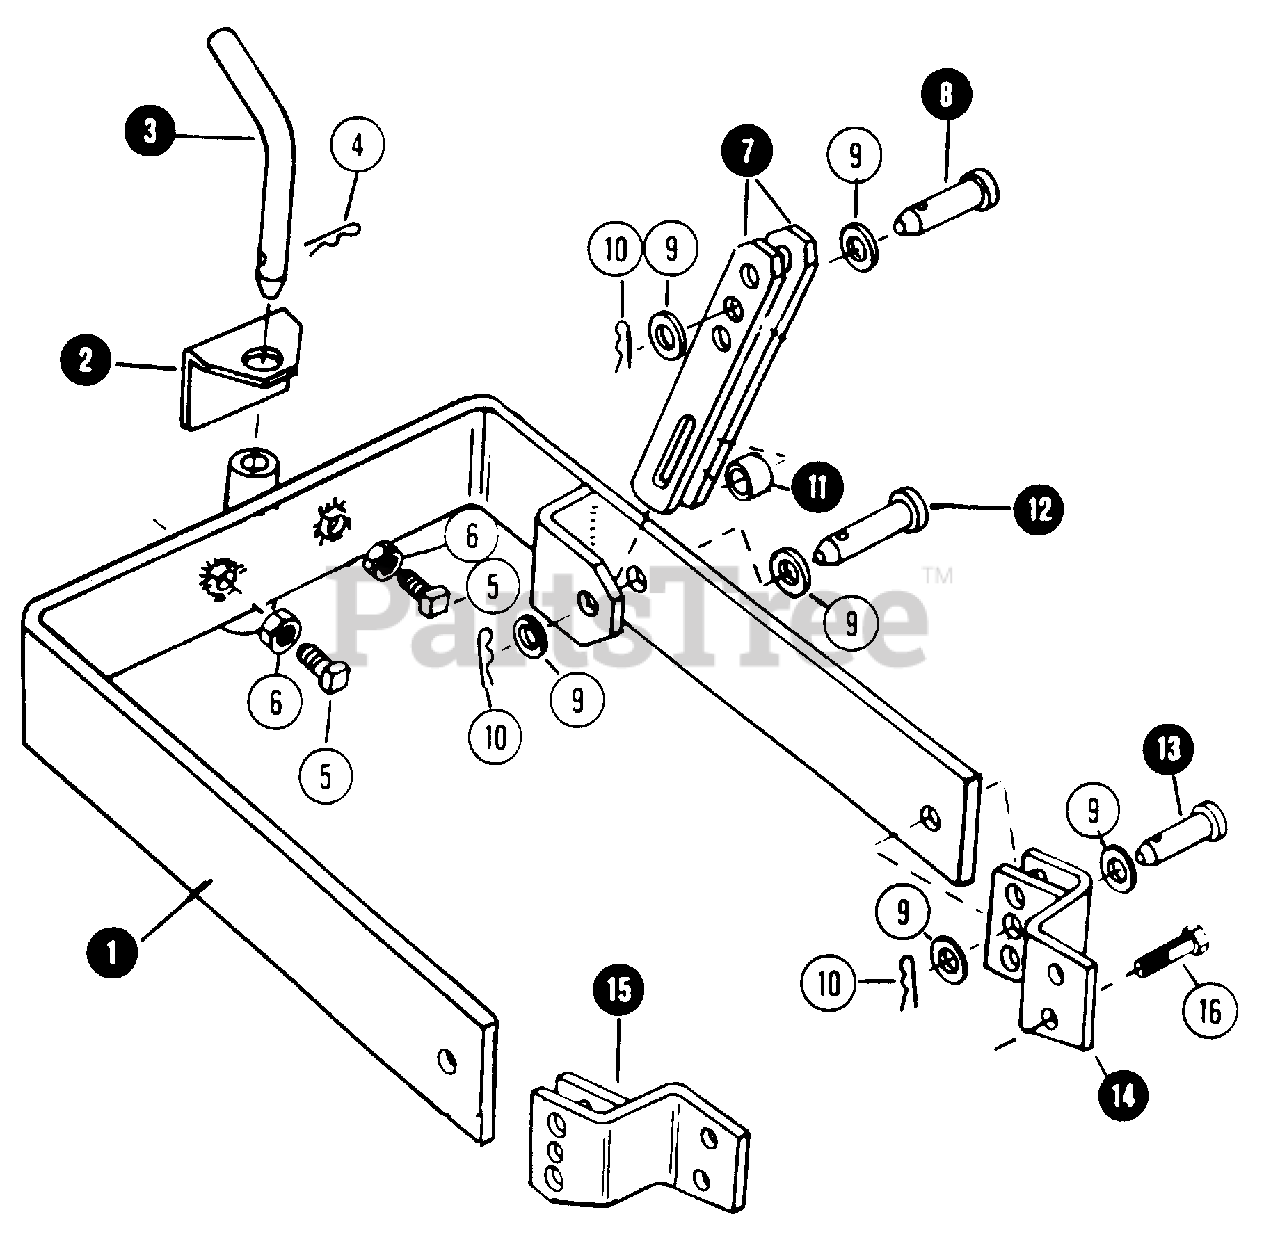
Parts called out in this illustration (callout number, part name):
1	BAIL, HITCH
2	STABILIZER, ADJUSTABLE
3	PIN, HITCH
4	PIN, HAIR
5	SCREW, 5/8C x 3 SQUARE HEAD SET
6	NUT, 5/8C HALF-HEX
7	LINK, UPPER
8	PIN, CLEVIS - LINK TO ROCKSHAFT
9	WASHER, 1/2 FLAT
10	PIN, HAIR
11	SPACER, 3/4 O.D. x 3/8
12	PIN, CLEVIS - LINK TO BAIL
13	PIN, CLEVIS - BAIL TO BRACKET
14	BRACKET, HITCH MOUNTING LEFT SIDE
15	BRACKET, HITCH MOUNTING RIGHT SIDE
16	BOLT, 3/8C x 7/8 HEX HEAD
